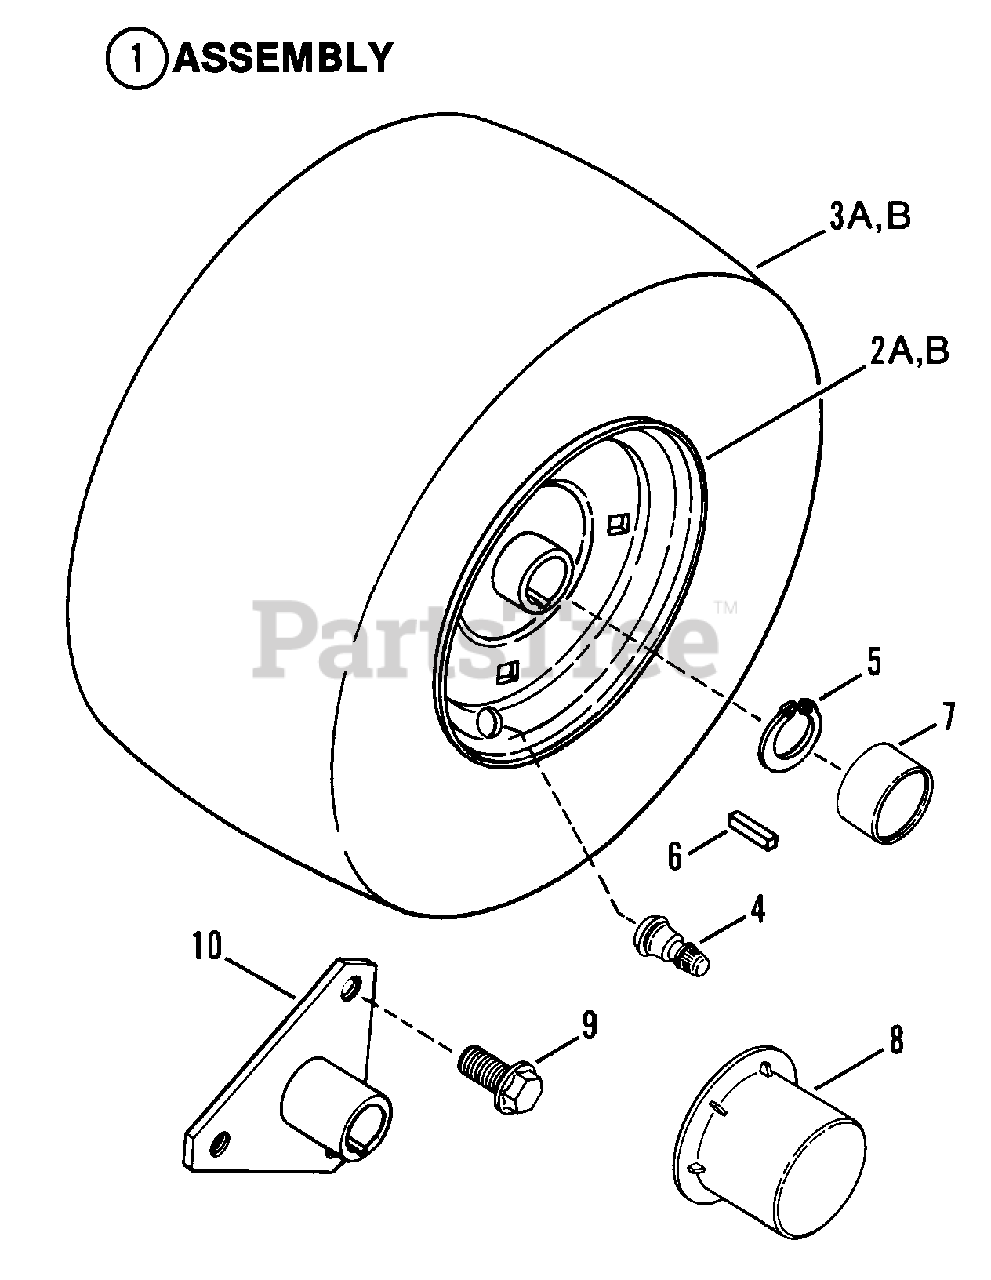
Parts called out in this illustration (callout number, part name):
1	ASSEMBLY, Rear Tire & Rim
2A	RIM, 10 x 5
2B	RIM, 12 x 9
3A	TIRE, 21 x 7.00 x 10
3B	TIRE, 23 x 10.50 x 12
4	VALVE, Air
5	RING, Retaining
6	KEY, 1/4 x 1/4 x 2" Square
7	COVER, Dust
8	HUB-CAP (33" Cutting Deck)
9	BOLT, 1/2-20 x 3/4" Lug (3)
10	HUB, Rear Wheel
